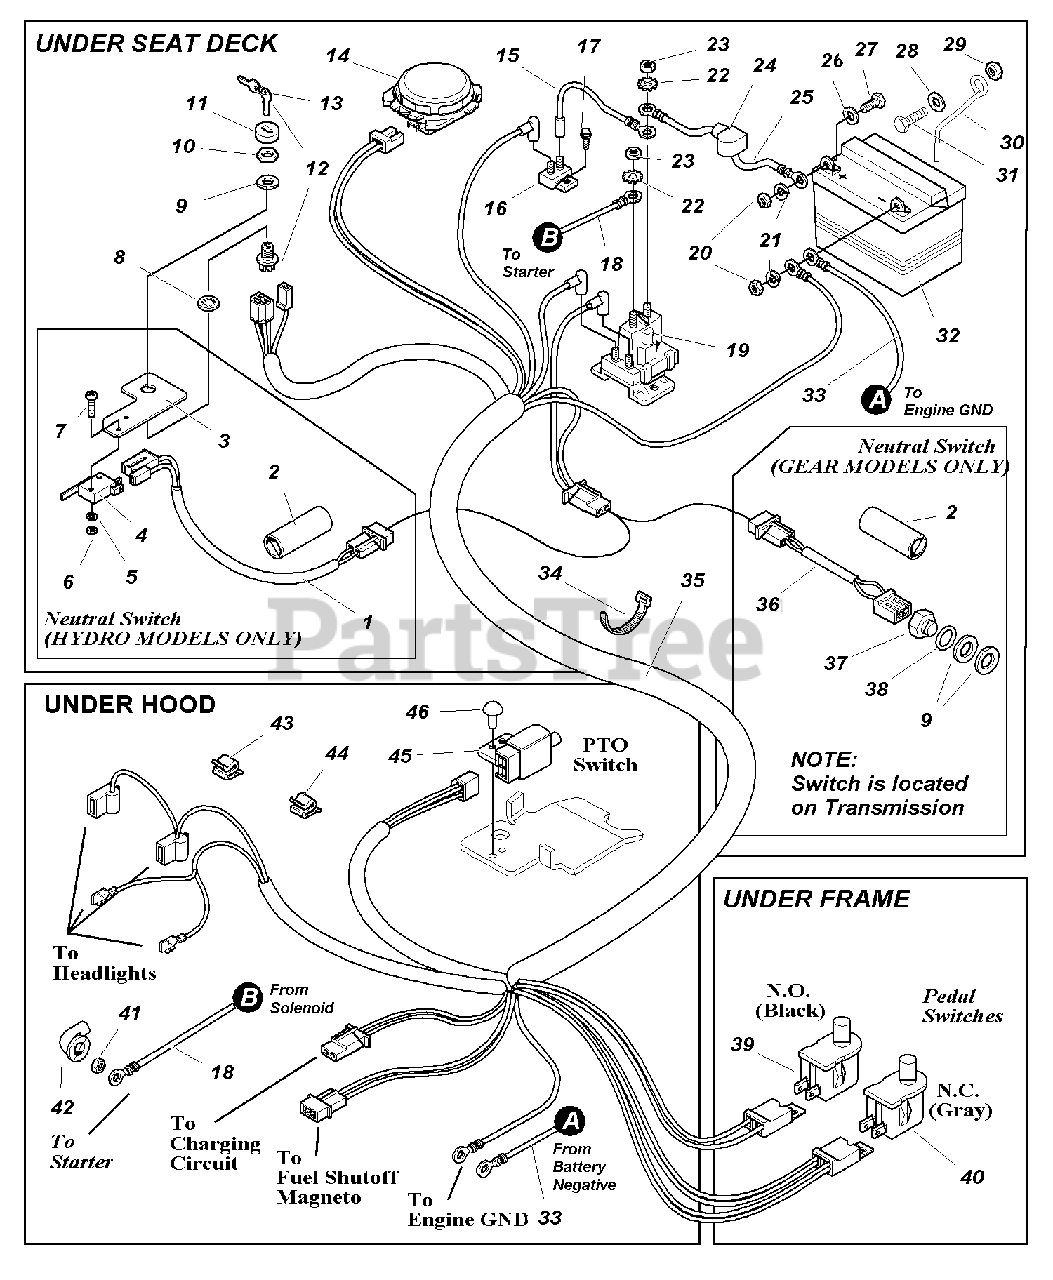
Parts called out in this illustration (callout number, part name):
1	WIRE ASSEMBLY (Hydro Models Only)
2	TUBE, Shrink
3	PLATE, Neutral Switch (Hydro Models Only)
4	SWITCH, Neutral Safety (Hydro Models Only)
5	LOCKWASHER, Spring, 1/8 (Hydro Models Only)
6	NUT, Hex Machine, #4-40 (Hydro Models Only)
7	CAPSCREW, Round Head, Phillips, #4 - 40 x 3/4
8	LOCKWASHER, Internal Tooth, 5/8
9	WASHER, 5/8
10	NUT, Hex, Flange, 5/8-32
11	COVER, Ignition
12	SWITCH, Ignition, 6-Pole (Includes Ref. 21, 23, 24, 25 & 26)
13	IGNITION KEY (Set of 2)
14	SWITCH, Seat, Gray Switch, Gray Retainer
14	SWITCH, Seat, Gray Switch, Black Retainer
15	WIRE ASSEMBLY
16	CIRCUIT BREAKER
17	CAPSCREW, Taptite Hex Washer Head, 1/4-20 x 5/8
18	CABLE, # 6 x 42-1/2 long (Solenoid to Starter)
19	SOLENOID
20	NUT, Hex, 1/4-20
21	LOCKWASHER, 1/4
22	LOCKWASHER, External Tooth, 5/16
23	CABLE, # 6 x 10 Long, with 2 Ring Terminals
24	BOOT, Insulator
25	NUT, Hex, 5/16-24 NF
26	WASHER, Plain, 1/4
27	CAPSCREW, Hex Head, 1/4-20 x 3/4
28	WASHER, Plain, 5/16
29	NUT, Hex Nylon Lock, 5/16-18
30	ROD, Battery Hold Down
31	CAPSCREW, Hex Head, 5/16-18 x 3/4
33	CABLE, # 6 x 52-1/2 long (Battery to Ground)
34	TIE-SELF LOCKING (Qty 2 on Gear Models)
35	HARNESS, Wiring
36	WIRE ASSEMBLY, Transmission (Gear Models Only)
37	SWITCH, Transmission
38	SEAL, O-Ring
39	SWITCH, Pedal, N.O., Black
40	SWITCH, Pedal, N.C., Gray
41	NUT, Hex Flange, Whiz Lock, 1/4-20
42	COVER, Terminal
43	CLIP, Tinnerman
44	CLIP, Wire
45	SWITCH, Neutral Start
